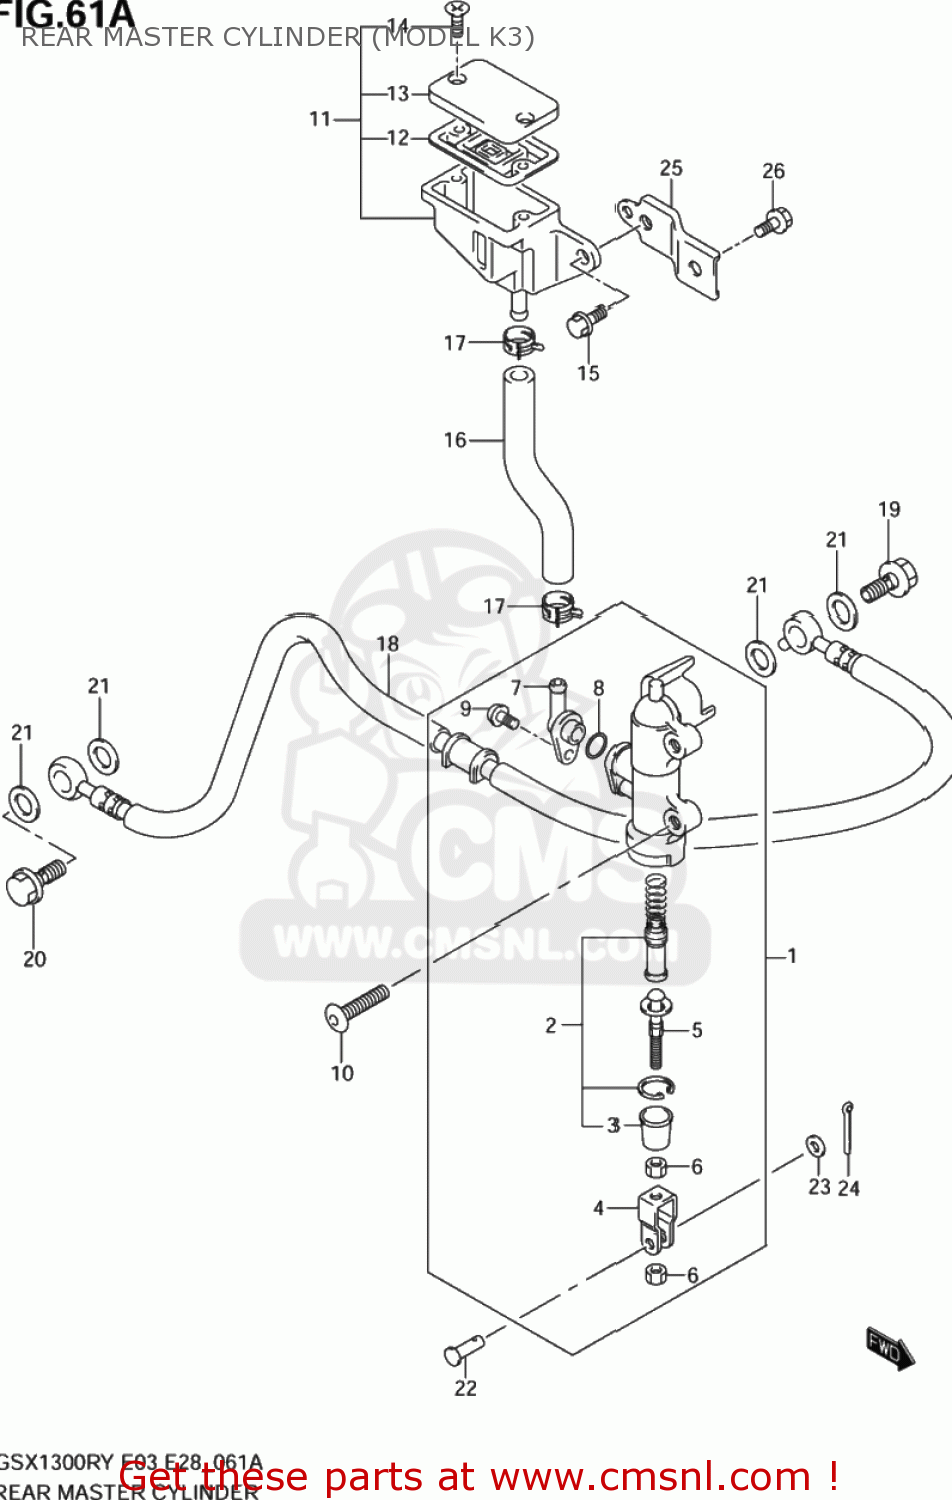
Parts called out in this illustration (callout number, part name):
1	CYLINDER ASSY,RR MASTER
2	PISTON/CUP SET
3	BOOT
4	YOKE
5	ROD,PUSH
6	NUT
7	CONNECTOR
8	O RING
9	SCREW
10	SCREW(6X20)
11	TANK ASSY,RR RESERVOIR
12	DIAPHRAGM
13	CAP
14	SCREW
15	BOLT
16	HOSE,RESERVOIR TANK
17	CLIP
18	HOSE,REAR BRAKE
19	BOLT UNION
20	BOLT UNION
21	WASHER(10X15X1.5)
22	PIN
23	WASHER
24	PIN
25	BRACKET,RR RESERVOIR TANK
26	BOLT
